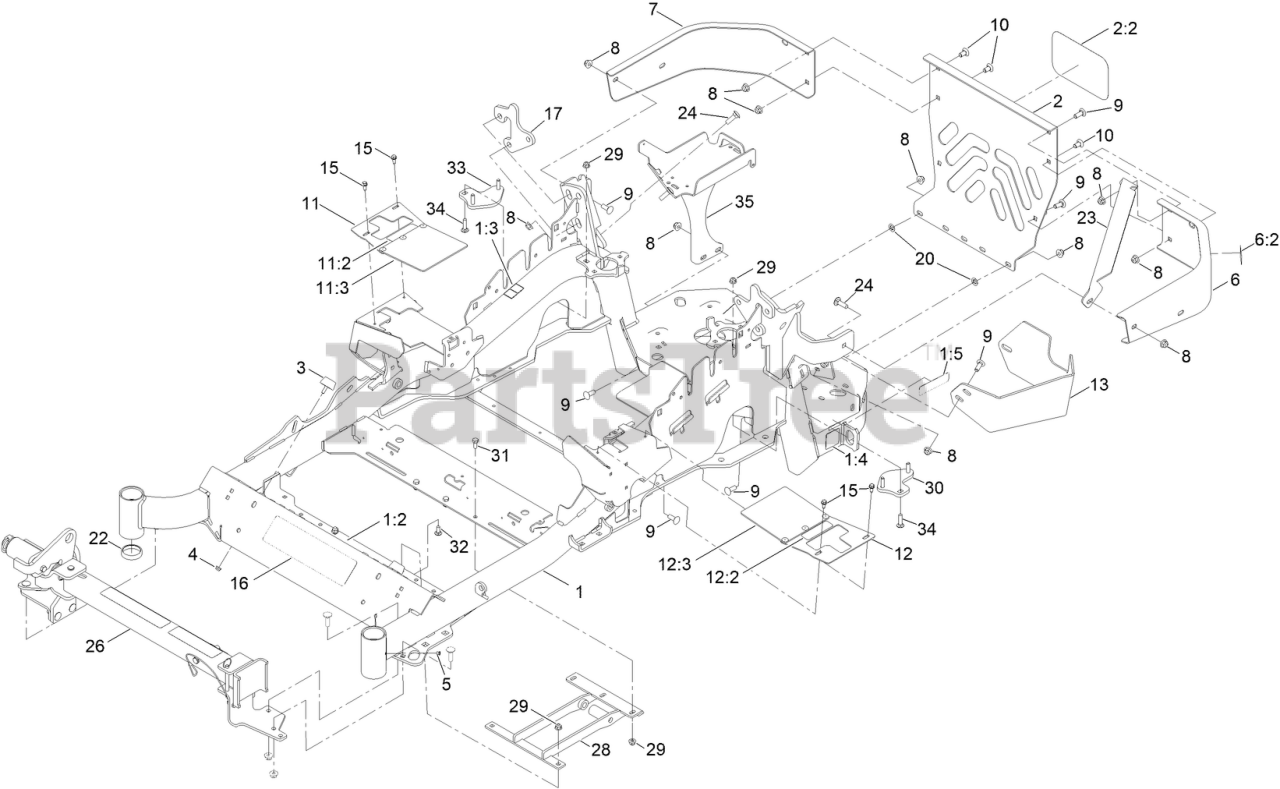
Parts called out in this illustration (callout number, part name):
1	MAINFRAME SERVICE ASM - 48/52
1:2	DECAL-DANGER
1:3	DECAL-WARNING
1:4	DECAL-HAZARD, PINCHED FINGER
1:5	DECAL-ARRESTOR, SPARK
2	REAR GUARD ASM
2:2	DECAL
3	BUMPER
4	NUT-HF
6	LH BUMPER ASM
6:2	DECAL-WARNING
7	BUMPER-RH
8	NUT-HF, NI
9	SCREW-CARR
10	SCREW-CARR
11	RH MOTION CONTROL COVER ASM
11:2	DECAL-CONTROL, MOTION
11:3	FLAP-RUBBER
12	LH MOTION CONTROL COVER ASM
12:2	DECAL-CONTROL, MOTION
12:3	FLAP-RUBBER
13	GUARD-MUFFLER
15	SCREW-HWH
16	DECAL-CONSOLE
17	PLATE-MOUNT, SHOCK
20	NUT-PUSH
22	CUP-BEARING
24	BOLT-CARR
26	Z STAND ASM
28	MOUNT-LOWER
29	NUT-HF, NI
30	LH PLATE ASM (W/STUDS)
31	SCREW-HH
32	SCREW-CARR
33	RH PLATE ASM (W/STUDS)
34	SCREW-CARR
35	BATTERY MOUNT ASM
